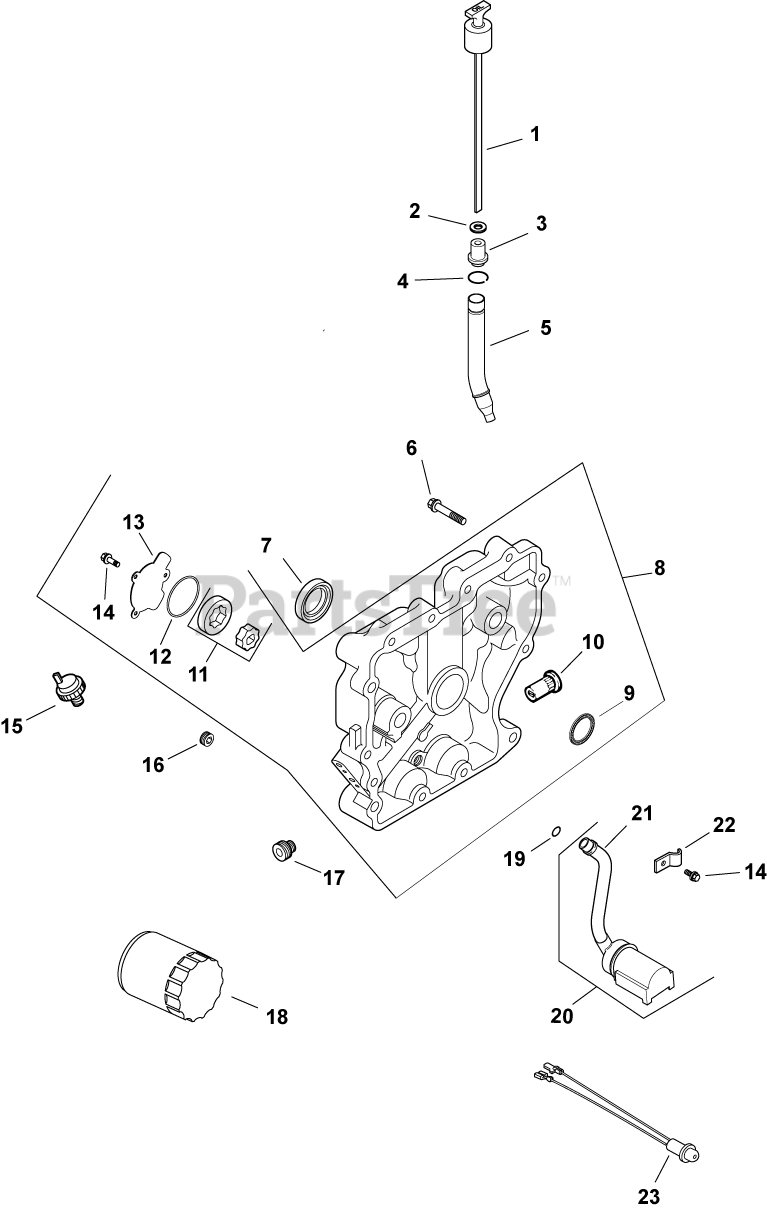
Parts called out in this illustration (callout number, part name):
2	SEAL USE 25 032 13-S
5	TUBE, OIL FILL - DISCONTINUED
6	SCREW, FLG M8X1.25X45
7	SEAL, OIL
8	PLATE, CLOSURE & BEARING
9	BEARING, CRANKSHAFT
10	VALVE, OIL PRESSURE RELIEF
11	PUMP ASSEMBLY, OIL
12	O-RING (1.78" DIA)
13	COVER, OIL PUMP
14	SCREW,FLG THD FRM M5X0.8X16-(#25086398S)
15	SENSOR, OIL PSI
16	PLUG, CTSK PIPE 1/8"
17	NIPPLE, OIL FILTER
18	OIL FILTER
19	O-RING (.5" DIA)
20	KIT, OIL PICK-UP
21	PICK-UP, OIL SCREEN
23	LIGHT, INDICATOR
